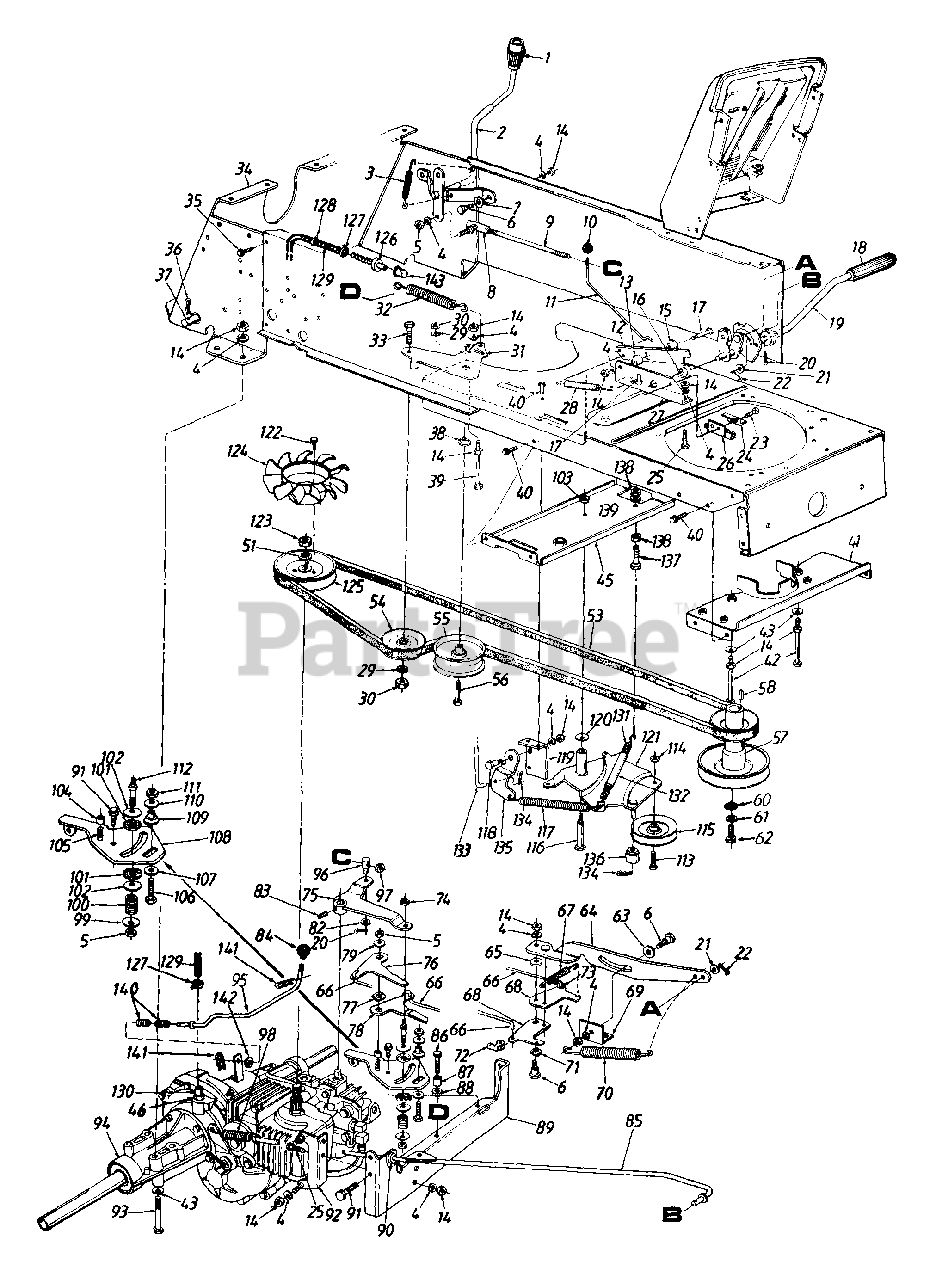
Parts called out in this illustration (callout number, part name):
1	Shift Knob
2	Speed Control Lever Ass'y.
3	Ext. Spring 2.75" Lg.
4	L-Wash. 5/16" I.D.
5	Hex Nut 5/16-24 Thd.
6	Shld. Bolt .437" Dia. x .268"
7	Spr. Wash. .445" I.D. x .75" O.D.
8	Ball Joint 5/16-24 Thd.
9	Speed Selector Adjusting Rod
10	Ball Knob
11	Brake Lockout Rod
14	Hex Nut 5/16-18 Thd.
15	Shld. Spacer .27" Lg.
16	Hex Flange Bearing
17	Hex Bolt 5/16-18 x 1.25" Lg.
18	Foot Pad
21	Fl-Wash. .34" I.D. x .68" O.D.
22	Cotter Pin 1/8" Dia. x 1" Lg.
23	Hex B-Tap Scr. #10 x .62" Lg.
24	Switch Plate
25	Hex Bolt 5/16-18 x .75" Lg.
26	Safety Switch (Clutch)
27	Clutch Ass'y. Mtg. Brkt.
28	Ext. Spring 2.51" Lg.
29	L-Wash. 3/8" I.D.
30	Hex Nut 3/8-16 Thd.
31	Idler Brkt.
32	Ext. Spring 4.75" Lg.
33	Hex Bolt 3/8-16 x 1.5" Lg.
36	Hitch Pin
37	Hitch Rod
38	Shld. Spacer .625" I.D.
39	Hex Bolt 5/16-18 x 2.75" Lg.
40	Hex Wash. Hd. TT-Tap Scr. 1/4-20 x .5" Lg.
43	Bell-Wash. .345" I.D. x .88" O.D.
45	Deck Idler Support Brkt.
46	O-Ring
53	"V"-Belt
54	Idler Pulley
55	Fl-Idler Pulley
56	Hex Bolt 3/8-16 x 2" Lg. (Gr. 8)
57	Engine Pulley
58	Sq.-Key 1/4" x 1.5" Lg.
60	Fl-Wash. .44" I.D. x 1.25"
61	L-Wash. 7/16" I.D.
62	Hex Cap Bolt 7/16-20 x 1.5" Lg.
63	Fl-Wash. .531" I.D. x 1.25" O.D.
64	Neutral Return Link Ass'y.
65	Fl-Wash. .344" I.D. x 1.12" O.D. (Hdn.)
66	Connecting Rod
67	Ext. Spring 2.5" Lg.
68	Balancer Brkt.
69	Bracket
70	Ext. Spring 3.94" Lg.
71	Spr.-Wash. .445" I.D. x .75" 0:D.
72	Rod End Clevis Clip - R.H.
73	Rod End Clevis Clip - L.H.
74	Hex Ins. L-Nut 3/8-24 Thd.
75	Pintle Bracket Ass'y.
76	Flat Scissors
77	Spr. Wash. .625" I.D. x .885" O.D.
78	Offset Scissors
79	Fl-Wash. .344" I.D. x 1" O.D. (Hdn.)
82	Fl-Wash. .406" I.D. x .75" O.D.
83	Hex Socket Set Screw
84	Ball Knob
85	Brake Rod Ass'y.
86	Hex Wash. Hd. Scr. 1/4-20 x 1.5" Lg.
87	Spacer .39" Lg.
88	Hex Nut 1/4-20 Thd. (Gr. 5)
91	Hex Wash. Hd. TT-Tap Scr. 5/16-18 x .62" Lg.
94	Transaxle
95	Bypass Rod
96	Ferrule 3/8-24 Thd.
97	Hex Jam Nut 3/8-24 Thd.
98	Ext. Spring 4.01" Lg.
99	Fl-Wash. .312" I.D. x .75" O.D.
100	Comp. Spring 1.19" Lg.
101	Friction Washer
102	Bell-Wash. .40" I.D. x 1.13" O.D.
103	Hex Cent. L-Nut 3/8-16 Thd.
104	Spacer
105	Rib Neck Bolt 5/16-18 x .62" Lg.
106	Hex Bolt 1/4-28 x 1" Lg. (Gr. 5)
107	Fl-Wash. .26" I.D. x .72" O.D.
108	Scissors Mtg. Brkt.
109	Centering Gauge Spacer
110	Bell-Wash. 1/4" I.D.
111	Hex Nut 1/4-28 Thd.
112	Friction Disc Stud
113	Hex Bolt 3/8-24 x 1.5" Lg.
114	Hex Cent. L-Nut 3/8-24 Thd.
115	V-Belt Idler
116	Shld. Bolt .498" Dia. x 2.05
117	Ext. Spring 6.12" Lg.
118	Shld. Bolt .437" Dia. x .162"
119	Parking Brake Mtg. Brkt.
120	Bell-Wash. .38" I.D. x .88" O.D.
121	Idler Brkt. Deck Ass'y.
122	Hex Wash. Hd. Tap Scr. #12 x 3/8" Lg.
123	Hex Jam Nut 9/16-18 Thd.
124	Fan
125	Input Pulley
126	Plastic Vent
127	Hose Clamp
128	Cable Tie
129	Hose 1/2" I.D. x 18" Lg.
130	Hose Fltting
131	Ext. Spring 6.37" Lg.
132	Convoluted Conduit
133	Deck Control Rod
134	Internal Cotter Pin
135	Deck Control Pivot Brkt.
136	Spacer
137	Hex Bolt 1/4-20 x 2" Lg.
138	Hex Nut 1/4-20 Thd.
139	L-Wash. 1/4" I.D.
140	Comp. Spring 1" Lg.
141	Hairpin Clip
142	Fl-Wash. 1/4" I.D.
143	Plastic Vent Cap
